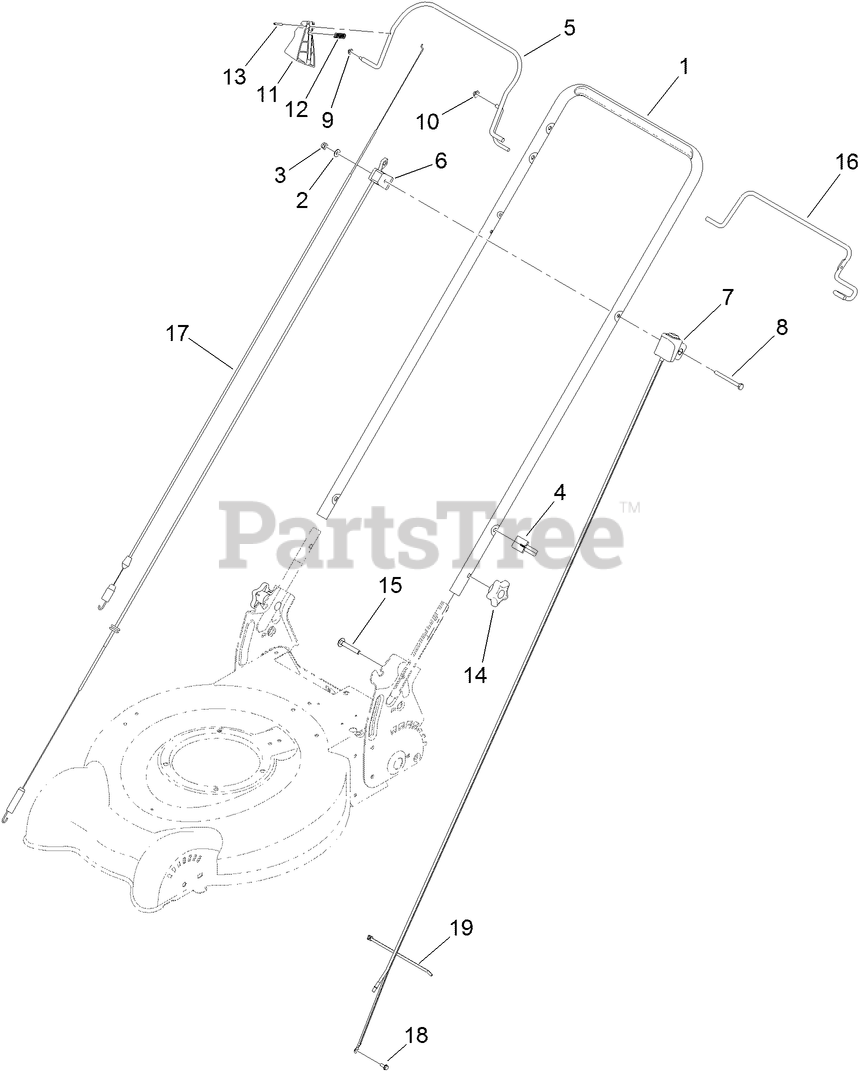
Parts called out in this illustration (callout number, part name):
2	WASHER-FLAT
3	NUT-LOCK, NI
4	GUIDE-CABLE
6	CABLE-BRAKE
7	SWITCH HOUSING ASM
8	SCREW-HH
10	NUT-SPEED
11	STOP-BAIL
12	SPRING-BRAKE
13	PIN-ROLL
14	KNOB-HANDLE
15	BOLT-CARR
16	BAIL-TRACTION, 2-BAIL FLAT
17	CABLE-TRACTION
18	SCREW-TAPTITE
19	TIE-CABLE
